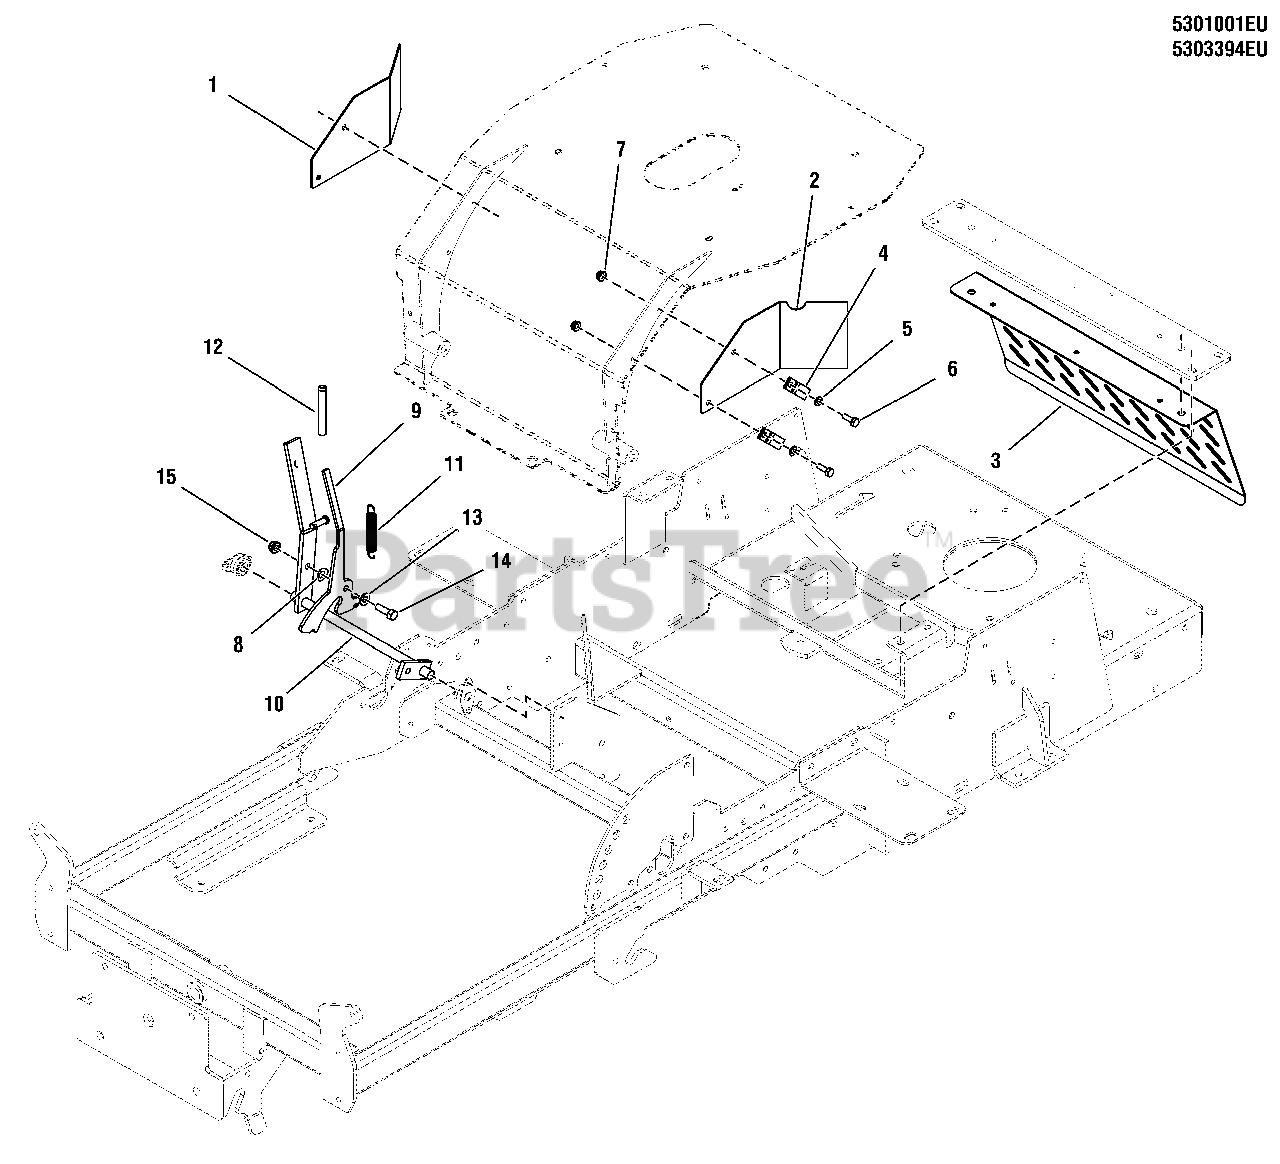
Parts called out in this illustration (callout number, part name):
1	GUARD, FRONT SEAT PLATE, RH - CONZ CE
2	GUARD, FRONT SEAT PLATE, LH - CONZ CE
3	GUARD, REAR SEAT SUPPORT - CONZ CE
4	CLAMP, VINYL COATED, 5/8 ID
5	WASHER, 1/4 SAE
6	BOLT, 1/4-20, GD5
7	NUT, 1/4-20 HEX NYLOCK FLANGE
8	WAVE WASHER, 10MM
9	LEVER, BREAK, CONZ - EU
10	WELD, SHAFT, BRAKE HANDLE, CONZ - EU
11	SPRING-EXT, .500ODX3.050LGX.058WR
12	COVER, VINYL HANDLE
13	WASHER, 5/16" SAE
14	BOLT, 5/16-18, GD5
15	NUT, 5/16-18 HEX NYLOCK FLANGE
